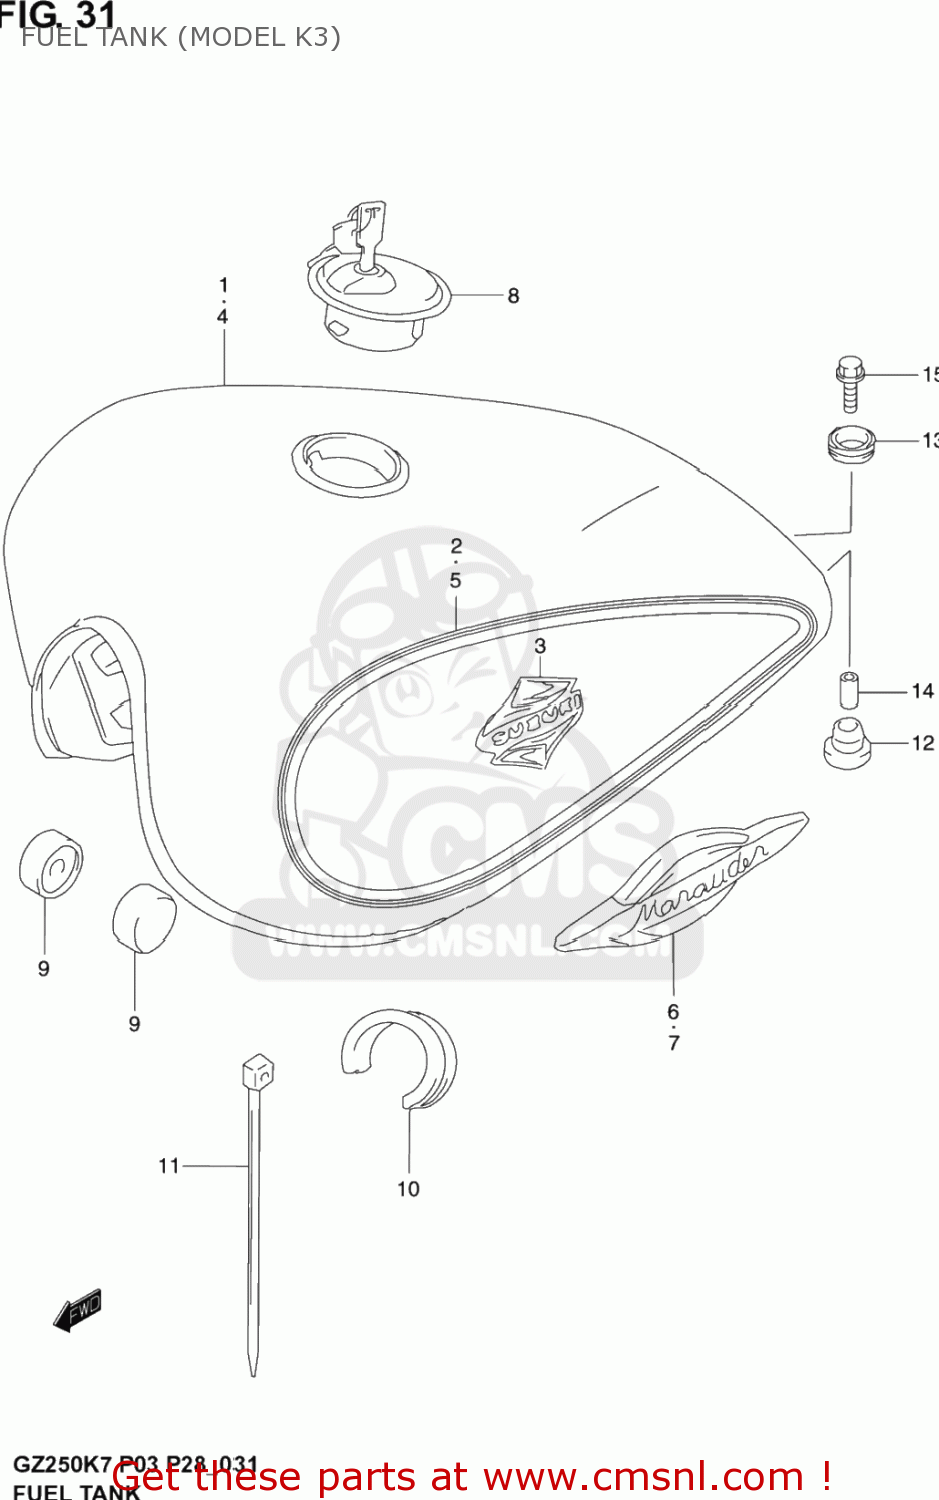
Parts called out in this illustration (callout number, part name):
1	TANK ASSY,FUEL(BLUE)
2	TAPE SET,FUEL TANK
3	EMBLEM,FUEL TANK
4	TANK ASSY,FUEL
5	TAPE SET,FUEL TANK
6	EMBLEM,TANK
7	EMBLEM. FUEL TANK LH
8	CAP SET,FUEL TANK
9	CUSHION
10	CUSHION,FUEL TANK SIDE
11	CLAMP
12	CUSHION
13	CUSHION,FUEL TANK RR
14	SPACER(6.5X9X18)
15	BOLT
